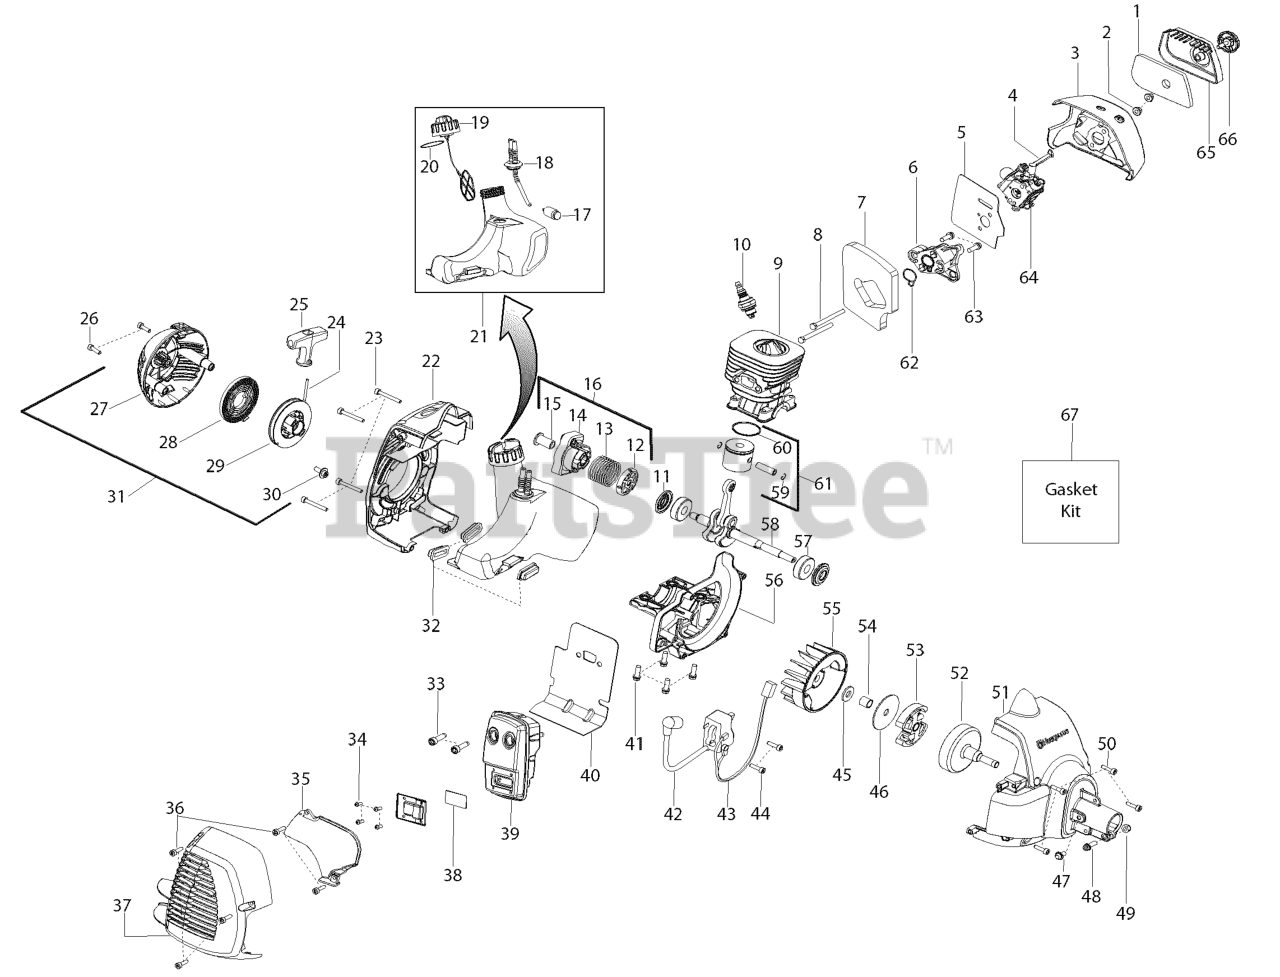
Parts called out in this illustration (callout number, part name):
1	FILTER AIRBOX
3	Air Box
4	CHOKE LEVER
5	KIT GASKET CARB
6	CARB ADAPTOR
7	KIT GASKET 28CC TRIMMER
8	BOLT CARB ADAPTOR
9	CYLINDER
10	Plug-Spark
11	KIT SEAL CRANKSHAFT
12	Washer - Starter
13	Spring - Starter Cup
14	Assy - Starter Cup
15	Coupling - Starter
16	COUPLING-STARTER
17	FUEL PICK-UP ASSY
18	KIT FUEL LINE
19	ASSY-CAP W/RETAINER
20	O RING NITRILE
21	FUEL TANK ASSY
22	REAR SHROUD
25	STARTER HANDLE GRAY
26	SCREW M5-0.8X30MM
27	STARTER HOUSING
28	%KIT STARTER SPRING
29	KIT STARTER PULLEY
31	ASSY-STARTER HSG.
32	ISOLATOR FUEL TANK
33	BOLT MUFFLER
34	SCREW-10-16 X 1/2 HI-LO
35	SHIELD HEAT
36	SCREW M4 X 1.75 PT 16MM
37	GUARD-MUFFLER
38	KIT SPARK ARRESTOR SCREEN
39	ASSY-MUFFLER
40	GASKET PAPER METAL
41	SCREW-M5-0.8 X 25MM(TAP)
42	IGNITION MODULE MB45
43	ASSY MODULE LEAD WIRE
44	SCREW M4 X .70 TT 16MM
45	WASHER CLUTCH
46	WASHER-CLUTCH
49	LOCKNUT-HEX 10-24
50	SCREW M4 X .70 TT 16MM
51	FAN HSG ASSY
52	Assy-Clutch Drum
53	%KIT CLUTCH ASSY
54	SPACER FLYWHEEL
56	CRANKCASE CASTING
57	BEARING RADIAL BALL (6201)
58	KIT CRANKSHAFT ASSY
59	WRIST PIN RET.
60	RING PISTON
61	KIT PISTON 28CC TRIMMER
62	KIT GASKET 28CC TRIMMER
63	SCREW-M5-0.8 X 25MM(TAP)
64	Kit-Carb.
65	COVER-AIR BOX
66	KNOB ASSY AIRBOX COVER
67	KIT GASKET 28CC TRIMMER
